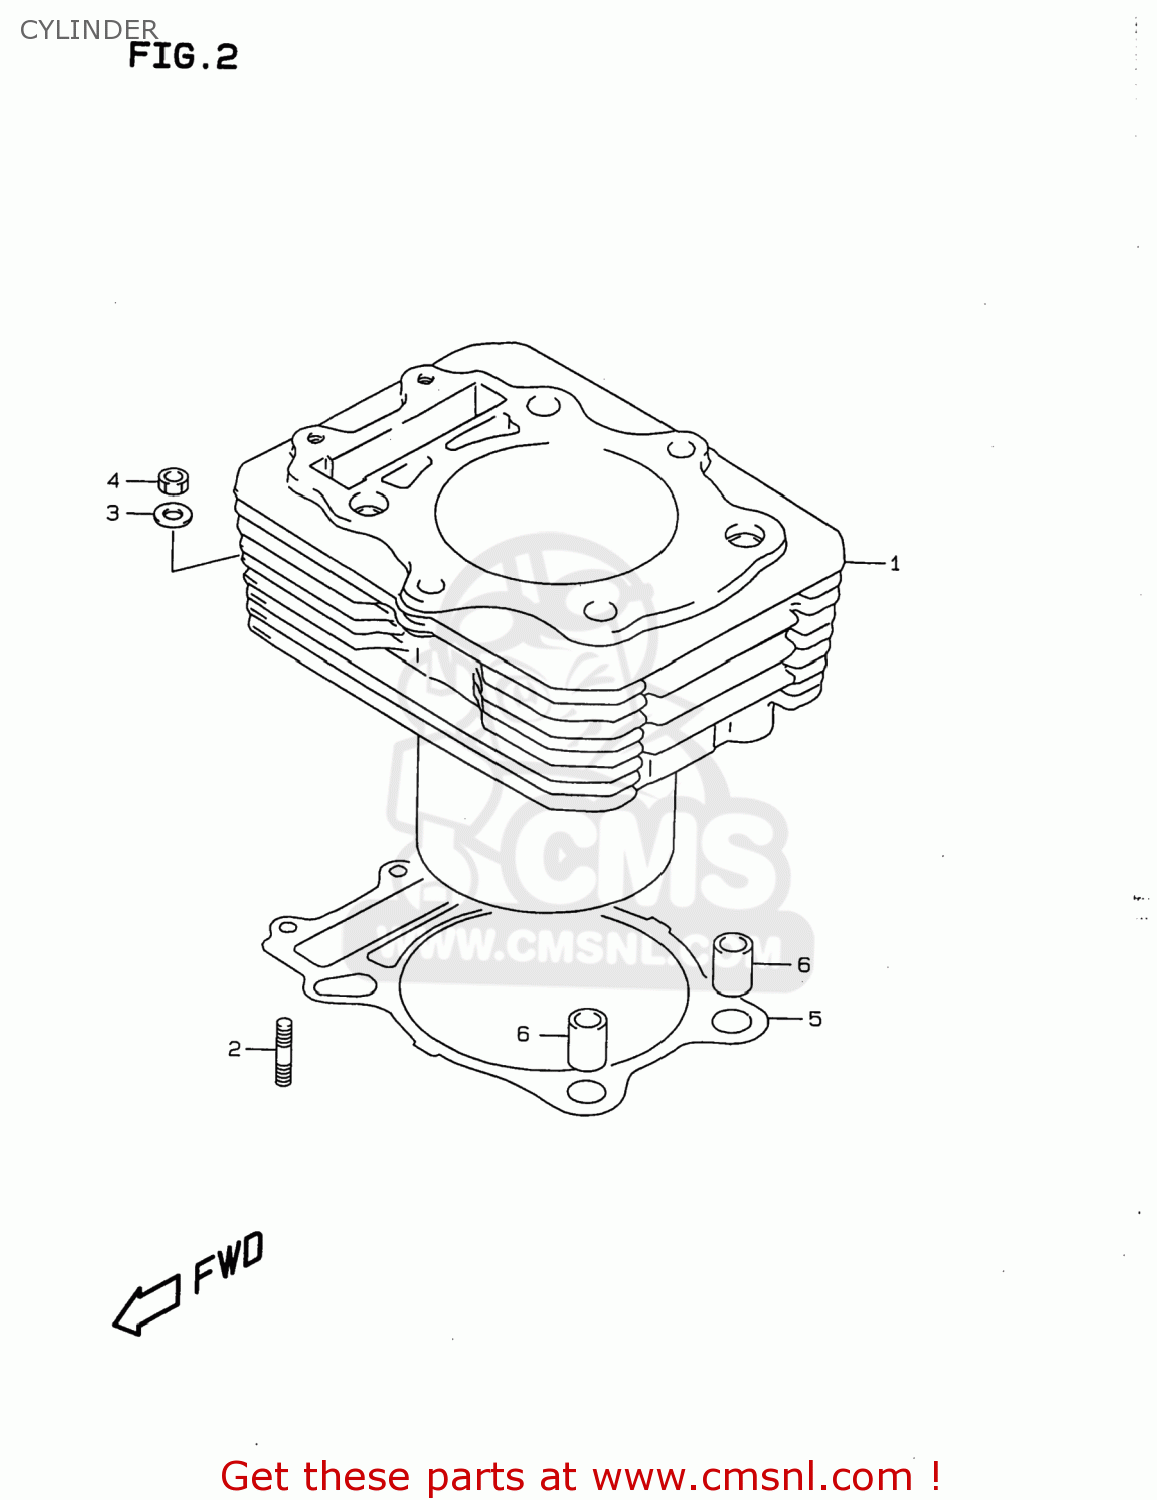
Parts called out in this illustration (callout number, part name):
1	CYLINDER
2	STUD 6X20
3	WASHER
4	NUT
5	GASKET,CYLINDER (NAS)
6	PIN
